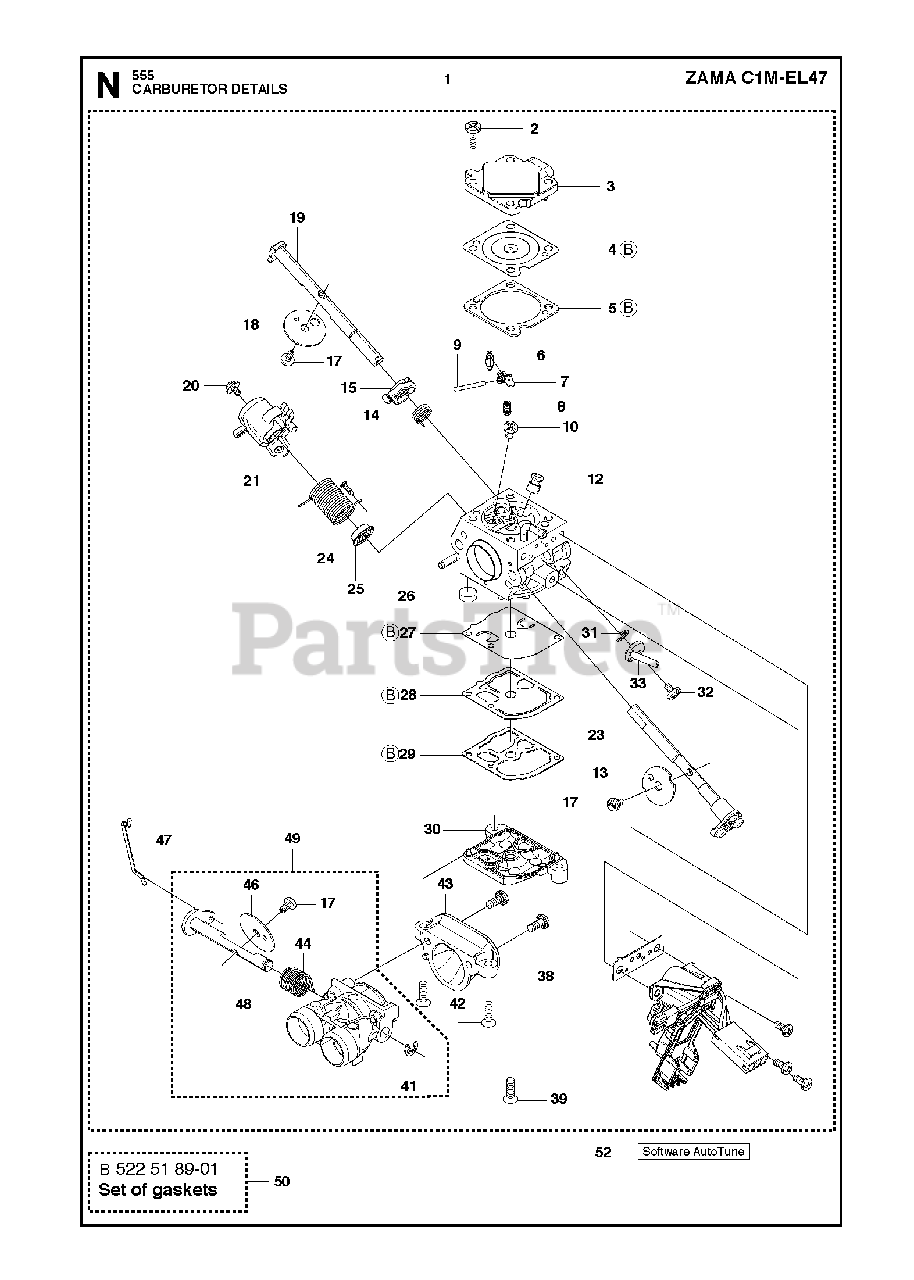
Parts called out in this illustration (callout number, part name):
1	CARBURETOR
2	SCREW
3	COVER
4	DIAPHRAGM
5	GASKET
6	INLET NEEDLE
7	LEVER
8	SPRING
9	PIN FULCRUM
10	SCREW
12	MAIN NOZZLE
13	VALVE
14	SPRING
15	LEVER
17	SCREW
18	CHOKE VALVE
19	SHAFT ASSY
20	SCREW
21	THROTTLE LEVER
23	THROTTLE SHAFT
24	SPRING
25	COLLAR
26	STRAINER
27	PUMP DIAPHRAGM
28	DIAPHRAGM
29	GASKET
30	COVER
31	CIRCLIP
32	SCREW
33	CHOKE LEVER
39	SCREW
41	CLIP
42	SCREW
43	INLET
44	SPRING
46	THROTTLE FLAP
47	ROD
48	SHAFT ASSY
49	THROTTLE VALVE ASSY
50	KIT GASKET AND DIAPHRAM
52	Husqvarna TBD
